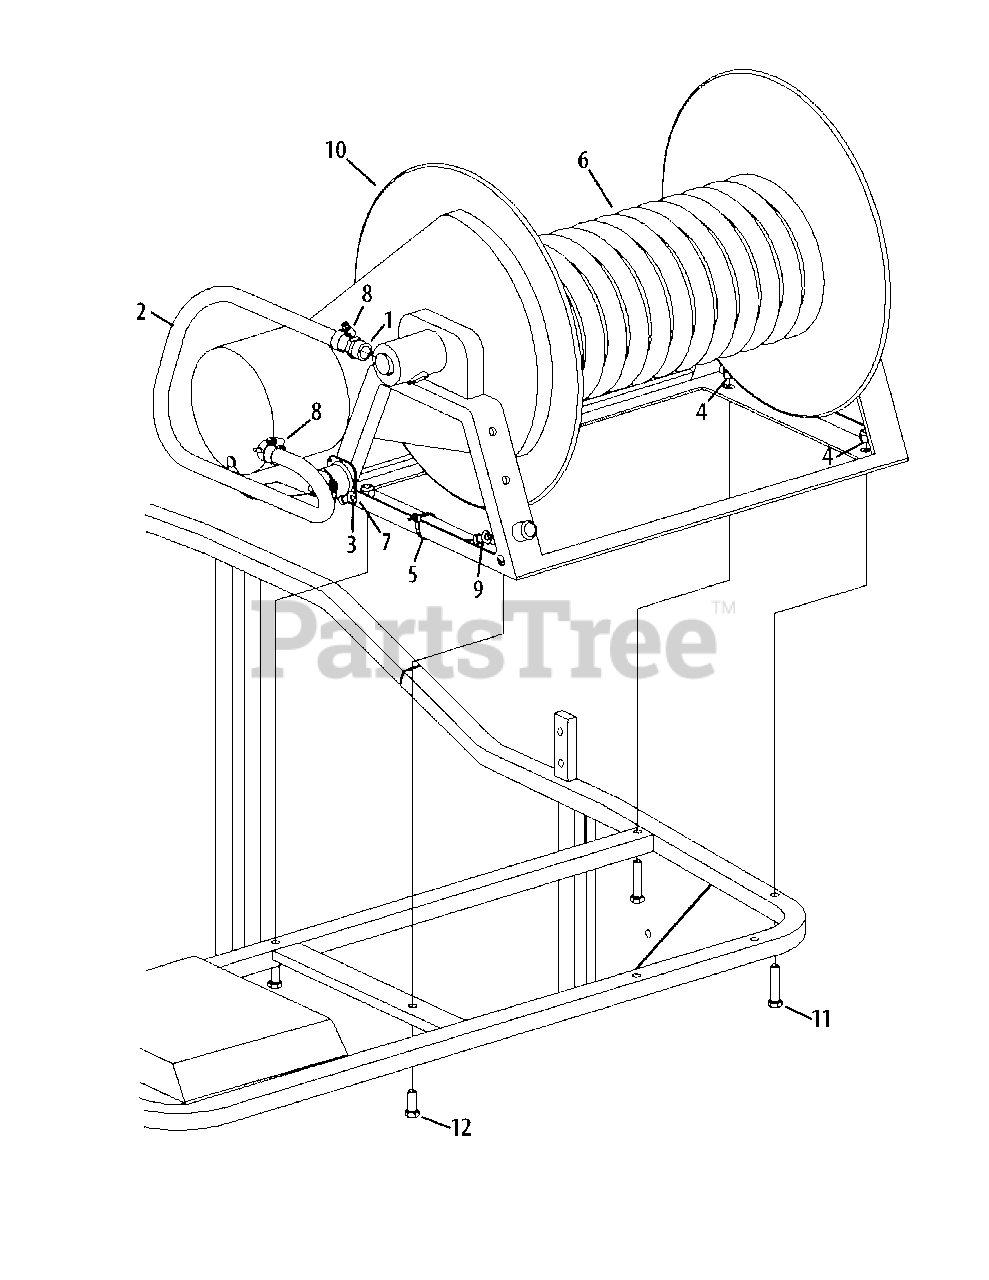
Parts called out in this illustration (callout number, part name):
1	Hose Barb, 1/2 x 1/2
2	Hose, 1/2
3	Ring Terminal, 3/8
4	Lock Nut, 3/8-16
5	Cable Tie
6	Hose Assembly, 1/2 x 300
7	Flat Washer, 1/4
8	Hose Clamp
9	Wiring Harness
10	Electric Hose Reel
11	Hex Screw, 3/8-16 x 1.75
12	Hex Screw, 38-16 x 1.00
